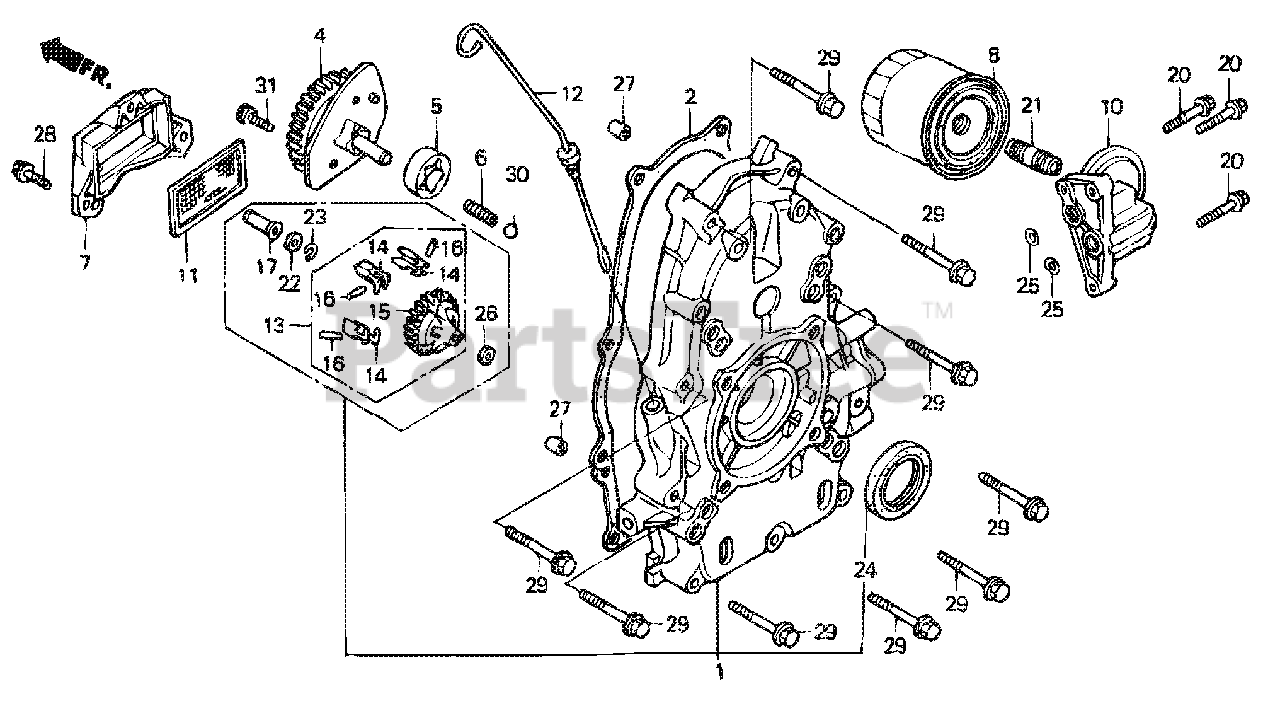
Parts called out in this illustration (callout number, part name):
1	Cover Assembly, Crankcase (Q-type)
2	Gasket, Case Cover
4	Cover Assembly, Oil Pump
5	Rotor, Oil Pump (Outer)
6	Spring, Relief Valve
7	Cover, Oil Filter
8	Filter, Oil
10	Base, Oil Filter
11	Screen, Oil Filter
12	Dipstick, Oil
13	Governor Assembly
14	Weight, Governor
15	Holder, Governor Weight
16	Pin, Governor Weight
17	Slider, Governor
20	Bolt, Flange (6x28)
21	Holder, Oil Filter
22	Washer (6x16)
23	Clip, Governor Holder
24	Oil Seal (38x58x9)
25	O-ring (11.8x2.4)
26	Washer, Plain (6mm)
27	Pin A, Dowel (8x14)
28	Bolt, Flange (6x20)
29	Bolt, Flange (8x50)
30	Ball, Steel (#12) (3/8)
31	Bolt, Socket (6x16)
